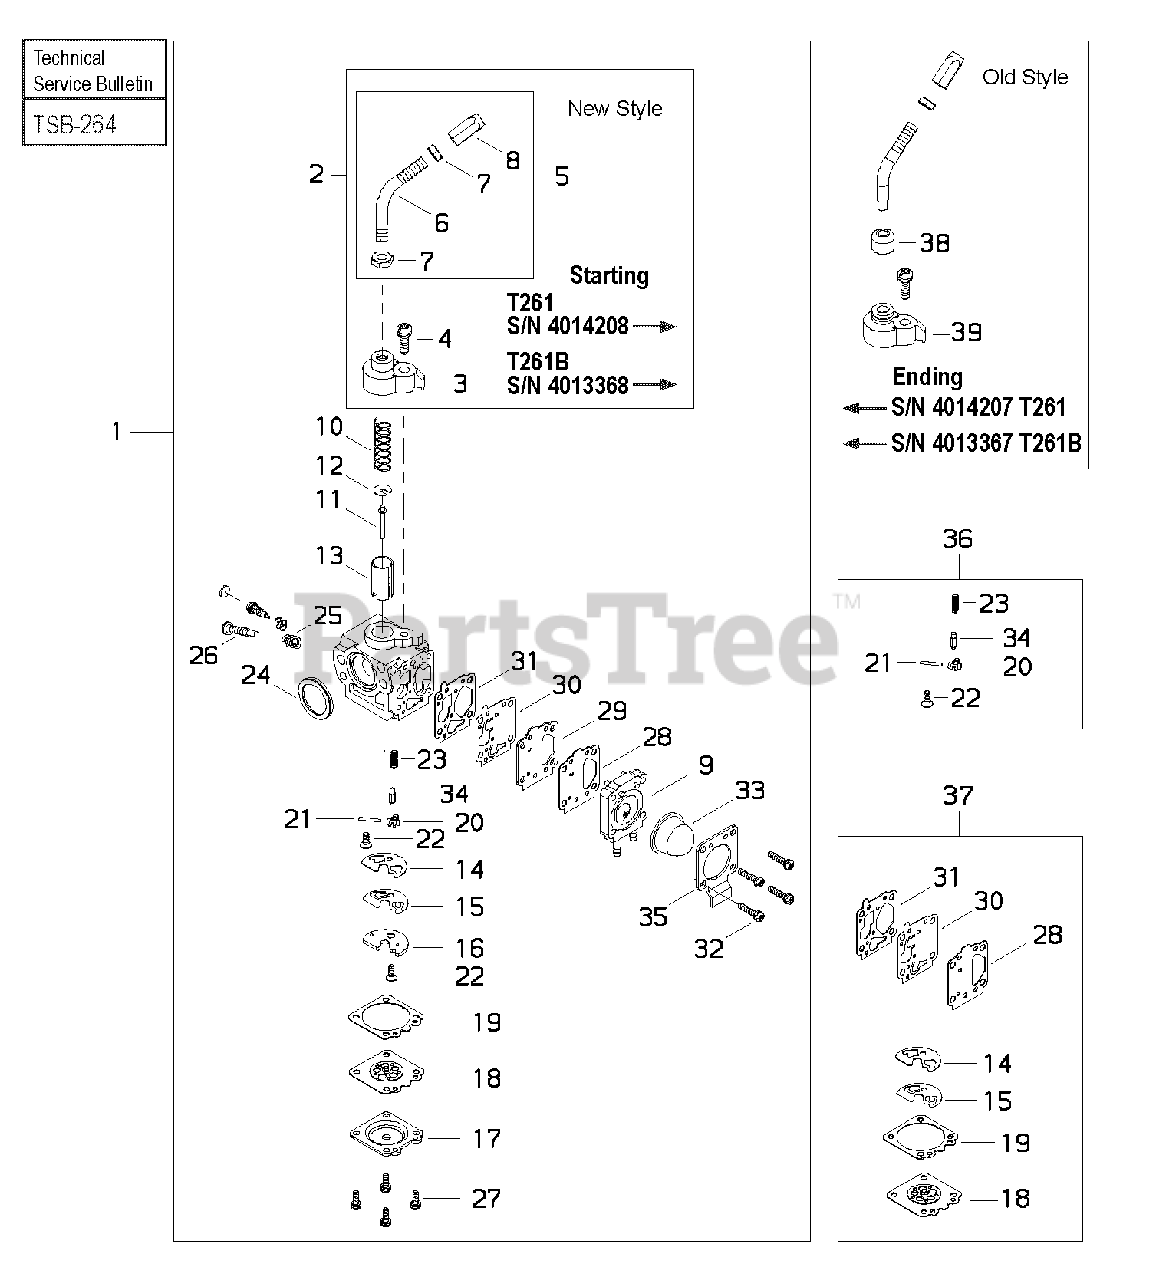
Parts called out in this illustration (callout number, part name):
1	CARBURETOR
2	CABLE ADJUSTER ASSY
3	CAP, CARBURETOR
4	SCREW - 5X15
5	ADJUST TUBE ASSY
6	TUBE, ADJUST
7	LOCKNUT
8	NUT, CABLE ADJUST
9	BASE, PURGE
10	SPRING, THROTTLE
11	NEEDLE, JET
12	RETAINER
13	VALVE, THROTTLE
14	GASKET
15	VALVE, CHECK
16	PLATE
17	COVER, DIAPHRAGM
18	DIAPHRAGM, METERING
19	GASKET, METERING
20	LEVER, METERING
21	PIN, METERING LEVER
22	SCREW, METERING LEVER PIN
23	SPRING
24	SEAL
25	SPRING
26	SCREW, IDLE ADJUST
27	SCREW
28	GASKET, PUMP
29	PLATE, PUMP
30	DIAPHRAGM, PUMP
31	GASKET, PUMP
32	SCREW - 3X14
33	BULB, PURGE
34	VALVE, INLET NEEDLE
35	COVER, PUMP
36	INLET NEEDLE VALVE KIT
37	DIAPHRAGM/GASKET KIT
38	GROMMET
39	CAP, CARBURETOR
